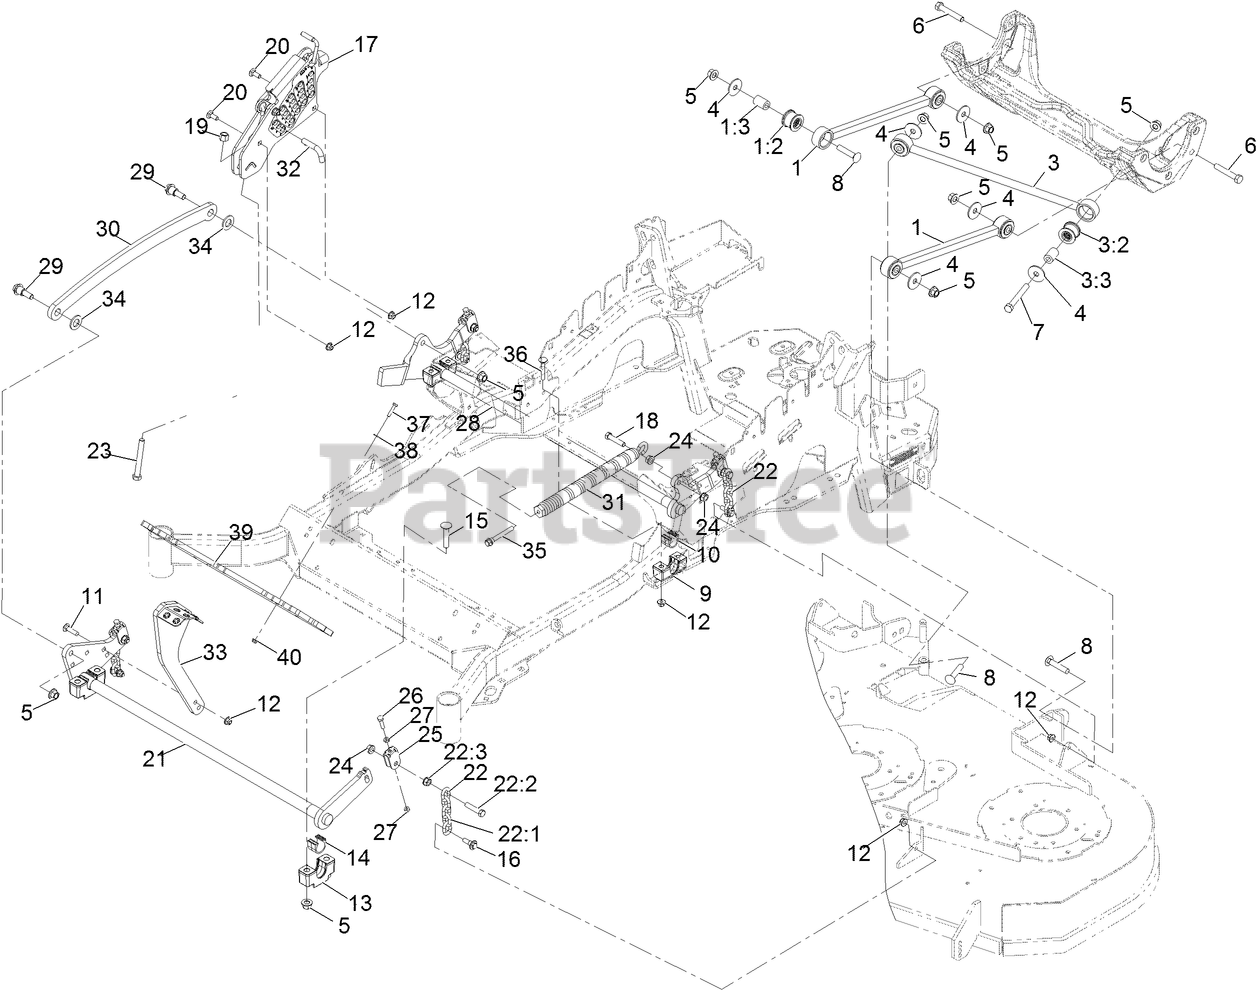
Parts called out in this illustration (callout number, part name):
1	LONG STRUT ASM
1:2	BUSHING-SUSPENSION, RUBBER
3	PANHARD ROD ASM
3:2	BUSHING-SUSPENSION, RUBBER
4	WASHER-THRUST
5	Nut-Lock 1/2-13
6	SCREW-HH
7	SCREW-HH
8	SCREW-CARR
9	SUPPORT-CROSS SHAFT, BEARING REAR
10	BEARING-CROSS SHAFT, REAR
11	SCREW-CARR
12	NUT-HF, NI
13	SUPPORT-CROSS SHAFT, BEARING
14	BEARING-CROSS SHAFT, FRON
15	Bolt-Carriage 1/2-13 X 2 1/2 Spl Neck
16	SCREW-SHOULDER, HHF
17	HOC ASM
18	SCREW-HH
19	NUT-LOCK, NI
20	BOLT-CARR
21	DECKLIFT-FRONT
22	DECK LIFT CHAIN ASM
22:1	CHAIN-LIFT, DECK
22:2	SCREW-HH
23	BOLT-TAP
25	YOKE-ADJUST, DECK
26	SCREW-HH
27	NUT-JAM
28	LIFT-DECK, REAR
29	SCREW-SHOULDER, HHF 1/2-13 X 1.12
30	LINK-LIFT, DECK
31	SPRING-EXTENSION
32	PIN-HOC
33	LEVER-FOOT
34	WASHER-FLAT
35	BOLT-SHOULDER
36	Bolt-Carriage 3/8-16 X 2 1/4
37	SCREW-HH
38	WASHER-FLAT
39	Weight-Toe Board
